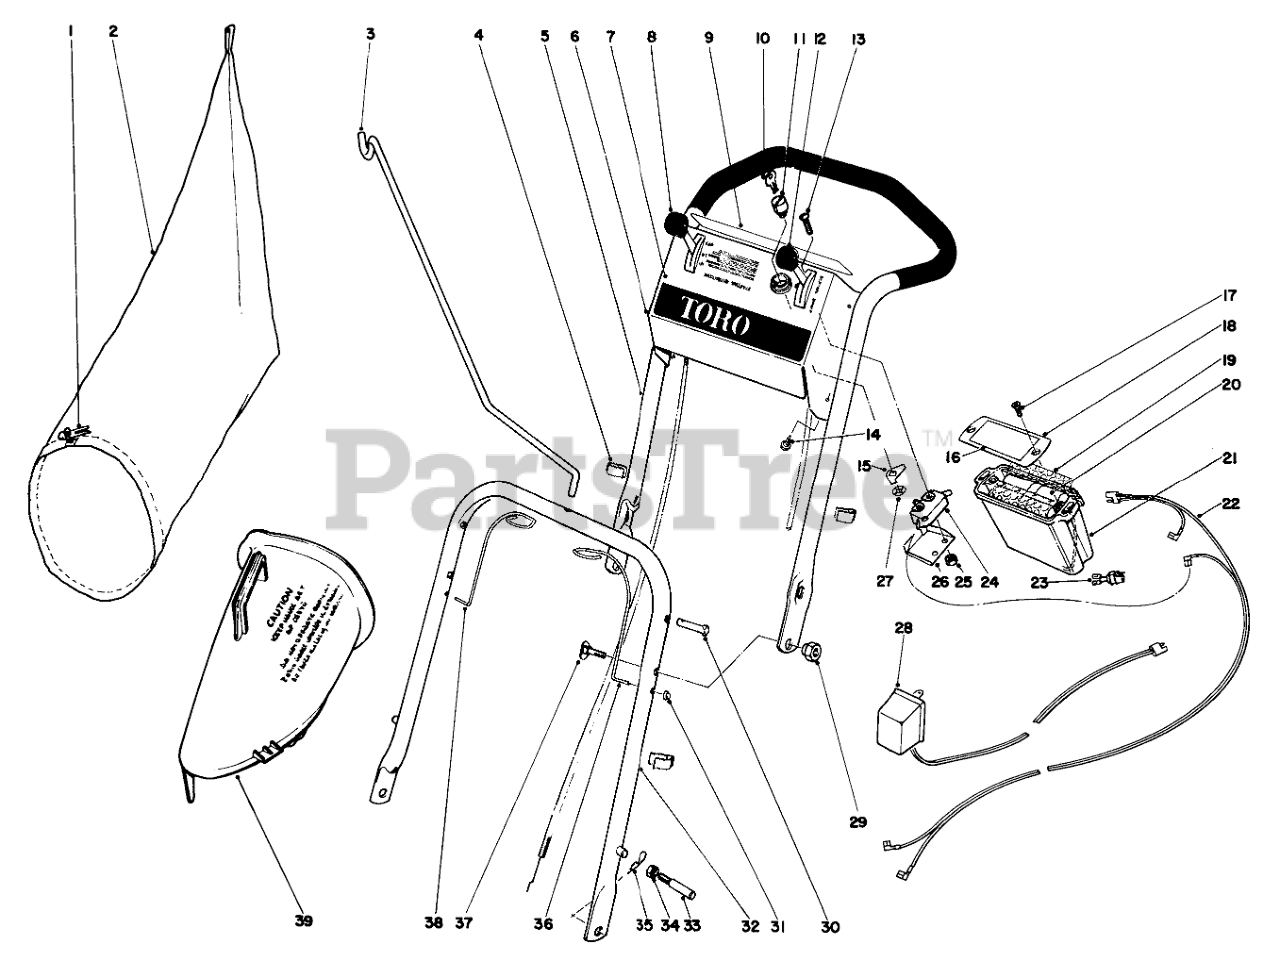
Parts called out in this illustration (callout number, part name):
1	BAG CORD FASTENER
2	Grass Bag (Incl. Ref. No. 1)
3	Bag Hanger Rod
4	BOWDEN CLIP
5	Upper Handle
6	Control Plate
7	Decal, Control Plate
8	Throttle Control
9	Decal, Safety
11	Key Hsg.
12	Traction Control
14	SCREW-HWHTF
16	Decal
18	Cover
19	Spacer
20	Battery Pack
21	Container Pack
22	Wiring Harness
23	Plug & Wire
24	Switch
25	NUT-KEPS
26	Cover Switch
28	Charger
29	Pivot Nut
30	Latch Pin
32	Lower Handle
33	Handle Pin
34	Nut
35	PIN-COTTER, HAIR
36	Latch Spring L.H.
37	HANDLE SCREW
38	Latch Spring R.H.
39	BAG ATTACHMENT
